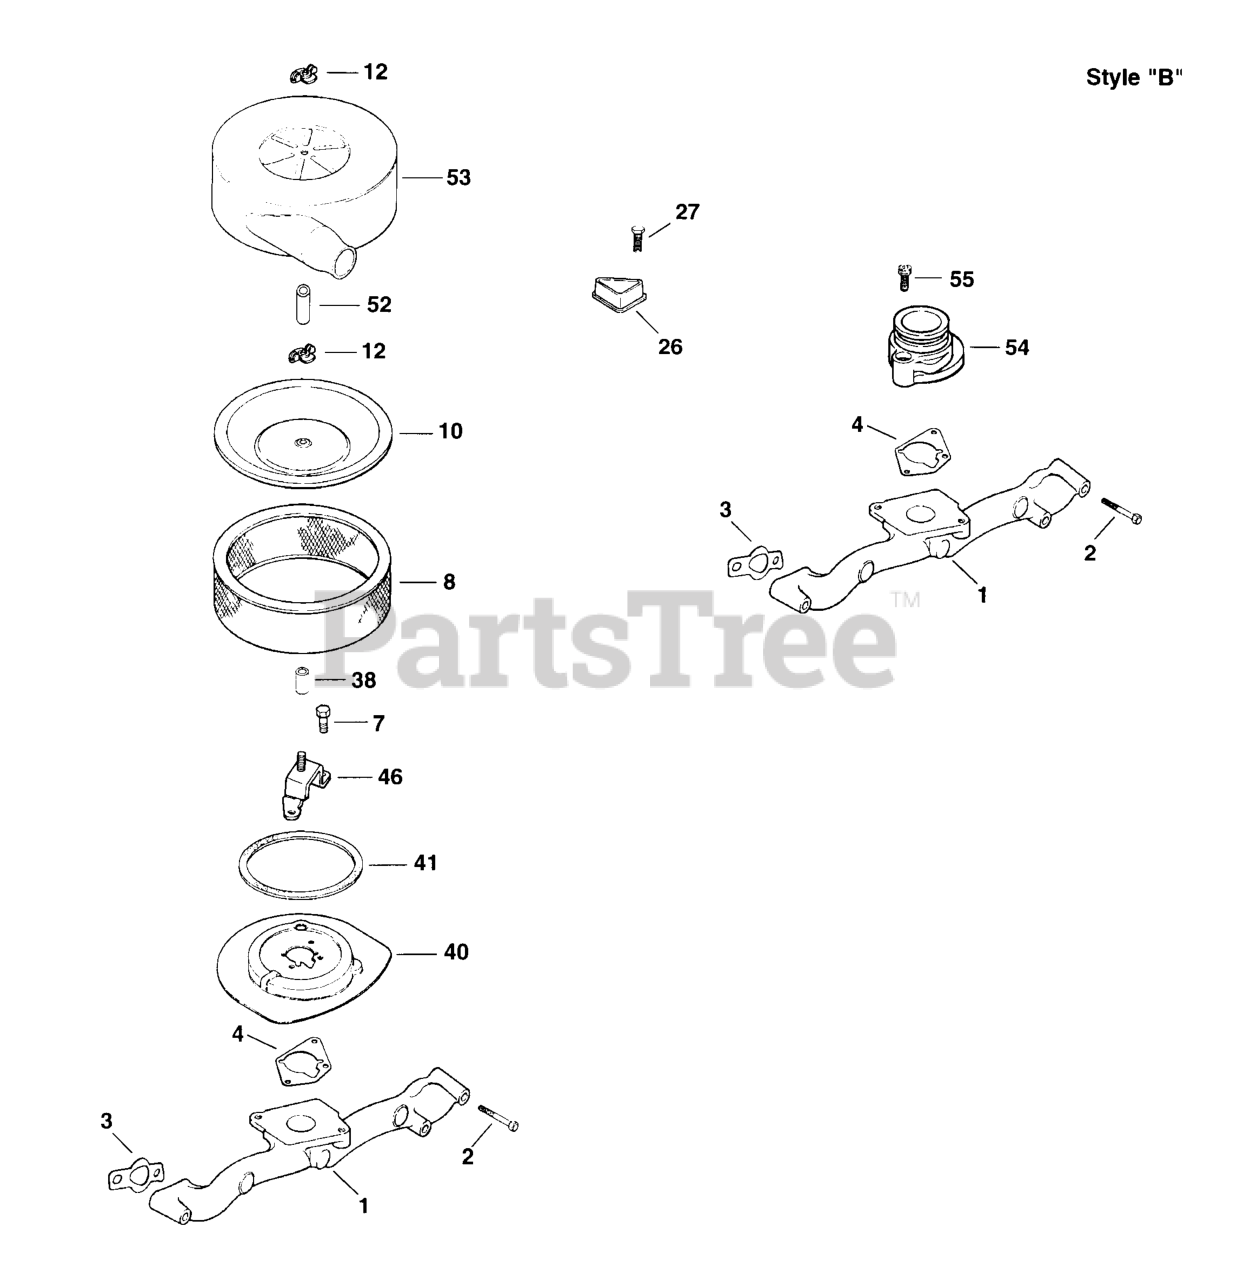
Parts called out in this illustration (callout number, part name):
1	MANIFOLD, METAL INTAKE
2	Screw, hex. flange M6x1.0x55
3	GASKET, INTAKE MANIFOLD USE 24 041 79-S
4	GASKET, AIR CLEANER BASE
26	COVER, BLOWER HOUSING USE 24 096 160-S
27	SCREW, WSH HD TAP #8-18X1/2" USE 25 086 91-S
54	ADAPTER, REMOTE - DISCONTINUED
55	Screw, hex. socket cap M6x0.8x25
